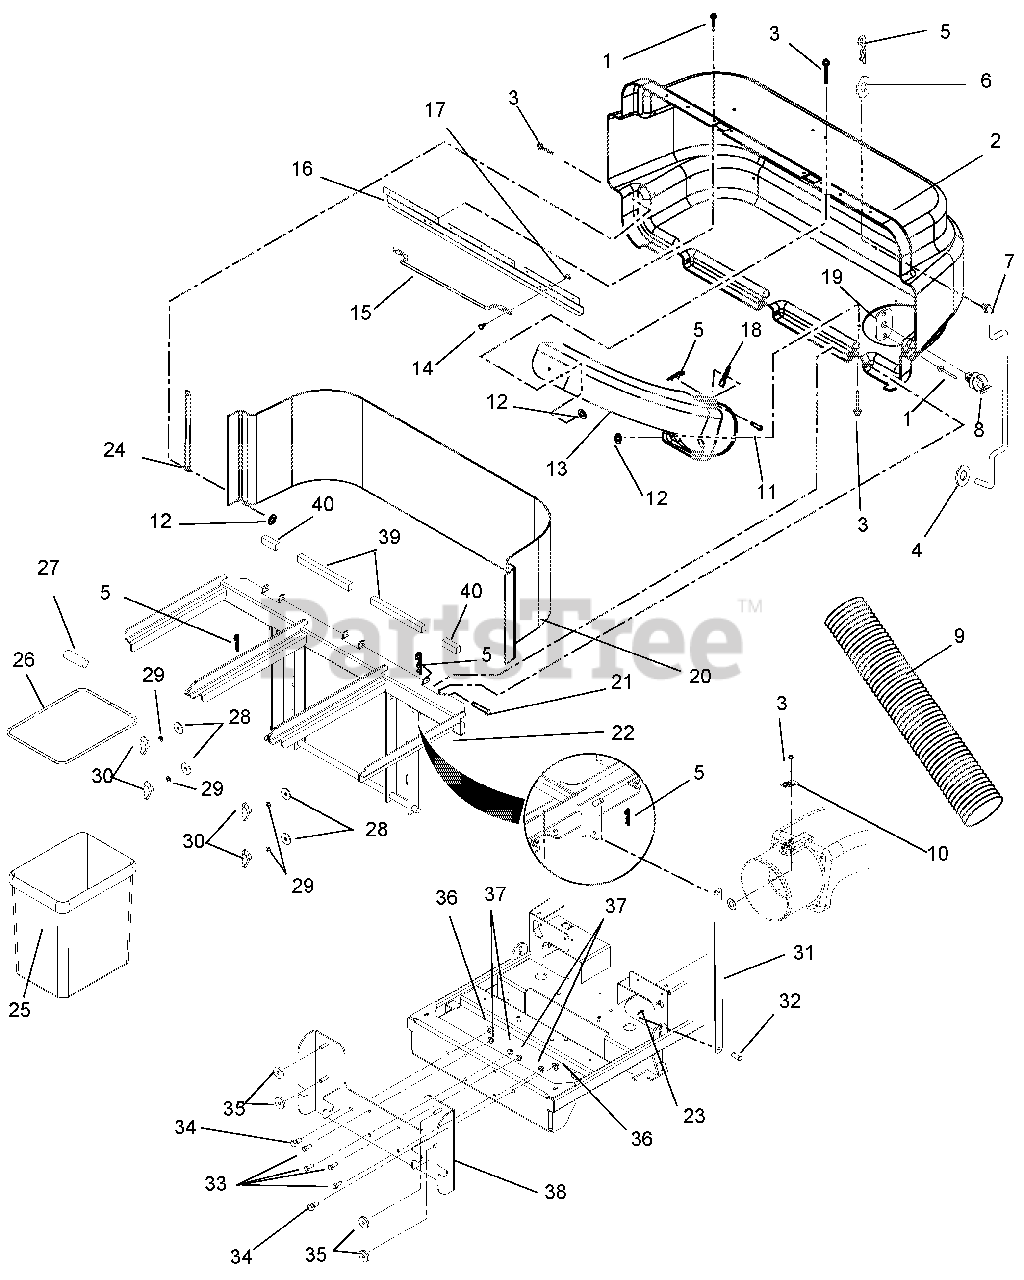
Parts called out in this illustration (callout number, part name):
1	RVT-POP .187X.402 DOME ST
2	ASM, BAGGER COVER
3	RVT-POP .187X.375
4	RETAINER, .38 PUSH-ON
5	PIN-HAIR, ENDRIES #25 YWZC
6	@WSHR-FL-STL.406X.812X.065 YWZ
7	PROP-ROD, BAGGER
8	CLIP-.38
9	HOSE, FLEXIBLE-47"
10	THUMB LATCH
11	PIN-CLEV .309 X 1.625 YWZC
12	@WSHR-FL-STL.219X.50X.049 YWZC
13	BOOT,UPPER
14	@BLT-RDHDSQNK .25-20X.75 G5YZ
15	BAGGER HANDLE
16	LATCH, BAGGER (ZOOM)
17	@NUT-LK-TOP-FLG .25-20 YWZC
18	INDICATOR, FLOW
19	PLATE, ROD CLIP
20	SCREEN, BAGGER
21	PIN-CLEV .371X3.25 YWZC
22	WMT, XL BAGGER FRAME
23	PIN, HAIR, EXT - #16 YWZC
24	STRAP,COVER
25	BAG, MESH XL BAGGER
26	FRAME, ZOOM BAG
27	HOSE, .38 X.50 X 3.00 VINYL
28	WSHR-FL-STL .390X1.5X.125 YWZC
29	@WSHR-LK .38X.094 REG YWZC
30	NUT-WING .38-16
31	STRAP, XL BAGGER
32	PIN-CLEV .38X.75 YWZC
33	@BLT-HEX .38-16X1.00 GR5 YWZC
34	@BLT-HEX .50-13X1.00 GR5 YWZC
35	WSHR,FLT STL.406X1.50X.245YWZC
36	@NUT-LK-NYL-FLG .50-13 YWZC
37	@NUT-LK-NYL-FLG .38-16 YWZC
38	WMT, MOUNTING PLATE
39	BLOCK, 10.5 IN FOAM GRASS
40	BLOCK, 4 IN FOAM GRASS
